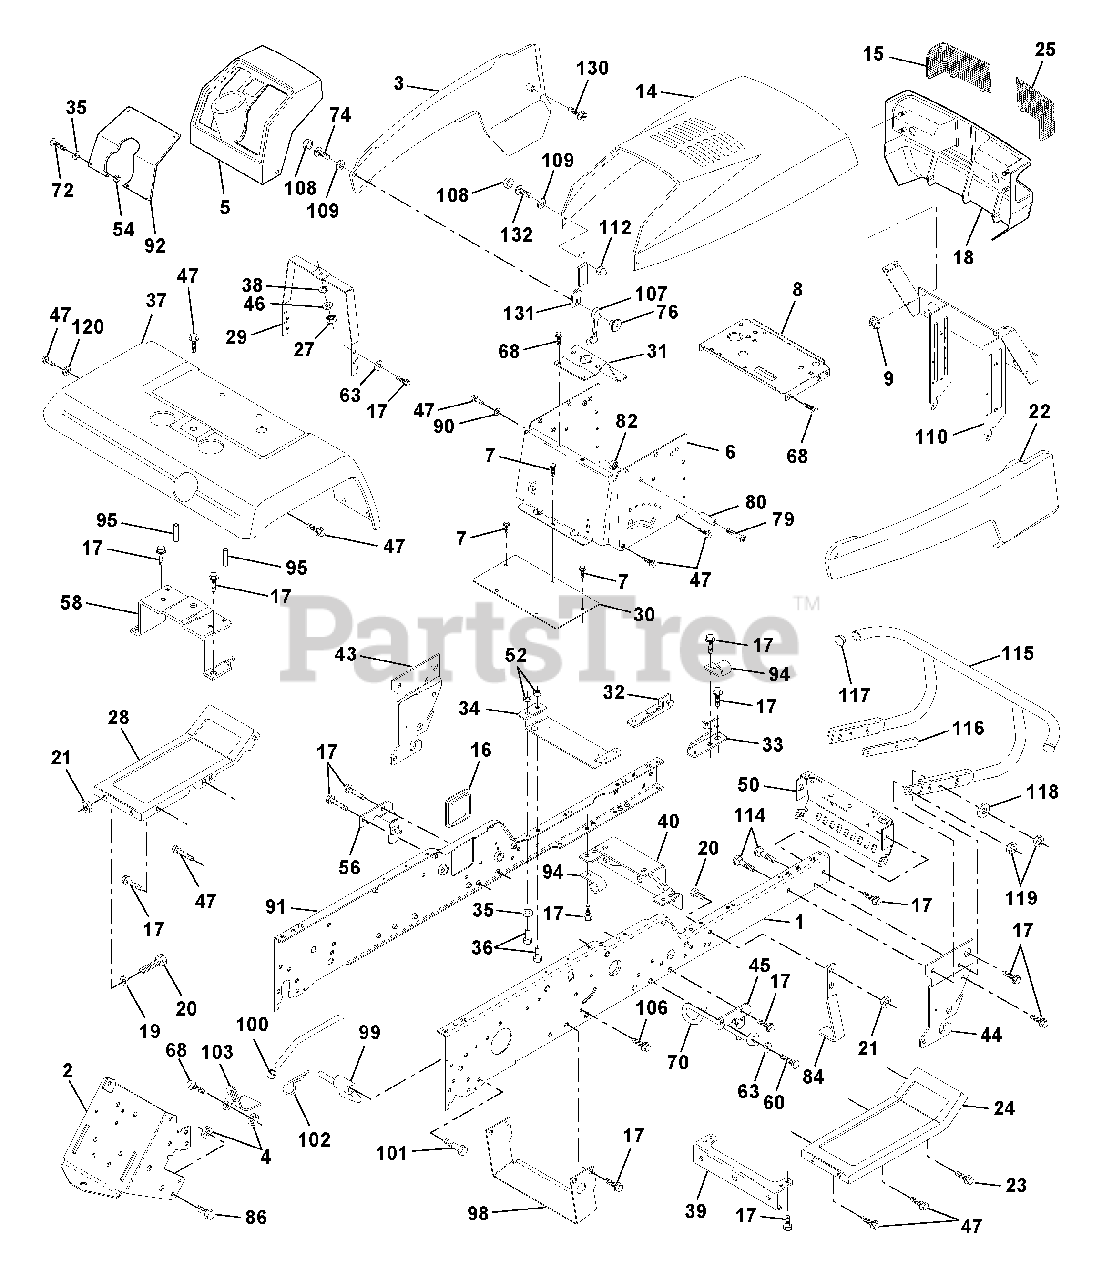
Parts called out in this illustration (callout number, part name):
1	Rail, Frame RH
2	Drawbar, Gt
3	Panel Asm., Side LH
4	Nut, Lock Hex 7/16 Unc
5	Dash, Plastic Black
6	Dash 1-PCS, Lower
7	Screw, Thd Cut 1/4-20 x 1/2
8	Support, Battery
14	Hood Asm., Pnt
15	Lens, Headlight LH
16	Cover, Access
17	Screw, Thdrol 3/8-16 x 3/4
18	Grille
19	Washer 13/32 x 13/16 x 12 Ga.
20	Bolt, Fin Hex 3/8-16 x 1
21	Nut, Crownlock 3/8-16 Unc
22	Panel Asm., Side RH
23	Screw Thdrol. 3/8-16 x 1 Ty-TT
24	Footrest, RH
25	Lens Headlight RH
27	Nut Fin Hex 1/4-20
28	Footrest, LH
29	Bracket, Support Dash
31	Brace, Support Steering
32	Bracket Asm., Frame Pivot Lh
33	Bracket Asm., Frame Pivot Rh
34	Bracket, Engine Support Rear
35	Washer 11/32 x 11/16 x 16 Ga.
36	Bolt, Fin Hex 5/16-18 x 3/4
37	Fender, Pnt.
38	Washer, Lock 1/4
39	Bracket, Axle Front
40	Bracket, Support Axle/Engine
43	Bracket, Spnsn Front Lh
44	Bracket, Spnsn Front Rh
45	Bracket Asm., Susp Chassis Rh
46	Washer 9/32 x 3/4 x 16 Ga.
47	Screw Thdrol 3/8-16 x 1/2
50	Bracket, Chassis Front
52	Locknut, Hex W/Ins 5/16-18 Unc
54	Nut 5/16-18
56	Bracket Asm., Susp Chassis Lh
58	Bracket Asm., Fender
60	Screw Thdrol 3/8-16 x 1-1/4
63	Washer 13/32 x 1 x 14 Ga.
68	Screw, Thdrol 5/16-18 x 1/2
70	Guide, Belt Mid Span
72	Screw, Mach Trhd 5/16-18 x 3/4
74	Screw, Machine #10-24
76	Nut, Weld #10-24
79	Screw, Machine #10-24 x 1/4
80	Spacer, Split
82	Nut #10-24
84	Stop, Over Center 44" 20/23" T. 94
86	Bolt, Fin Hex 7/16-14 Unc x 1
90	Washer, Lock External Tooth 3/8
91	Rail, Frame Lh
92	Plate, Silkscreen Dash
94	Clip, Fuel Line
95	Push Nut, Nylon
98	Bracket Chassis Skid
99	Rod Asm. Bypass
100	Cap Brake Parking Red
101	Screw Thdrol. 3/8-16 x 1-3/4
102	Retainer Spring 1"
103	Bracket Lock Bypass
106	Screw Thdrol. Hex Hd Zinc Mur
107	Latch, Chute Blk
108	Cap, Snap Black
109	Cap, Washer Snap
110	Pivot Asm. Grille/Hood Husq. VGT
112	Nut, Acorn, Hex #10-24
114	Bolt, Carriage 3/8-16 x 1-1/4
115	Bumper Asm.
116	Bracket Extension Bumper
117	Plug Plastic
118	Washer 13/32 x 13/16 x 16 Ga.
119	Nut Crownlock 3/8-16 UNC
120	Washer 13/32 x 1 x 16 Ga.
130	Screw, SLTD Hex Hd. W/Pl Washer
131	Bracket Support Hood/Panel YP
132	Screw Truss Hd. #10-24 x 3/8
